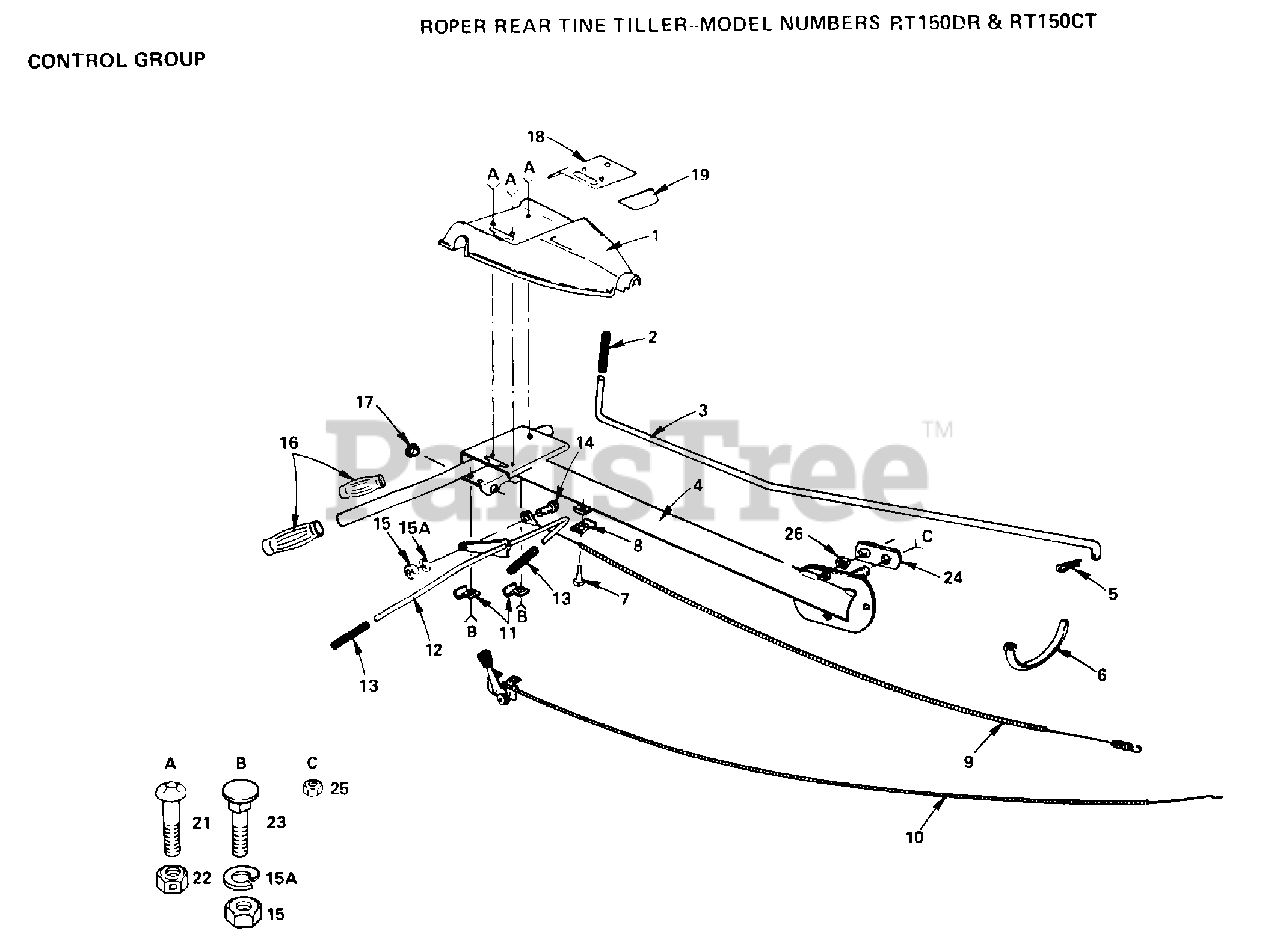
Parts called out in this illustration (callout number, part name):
1	PANEL - CONTROL
2	GRIP TI
5	RETAINER M
6	TIE CABLE CRT
7	SCREW TI
8	CONDIUT CLIP T
9	CABLE.CLUTCH.CRT
10	CTRL-THROTTLE T
13	GRIP BAR CRT
14	SHOULDER BOLT ST
15A	LOCKWASHER
17	GROMMET TI
18	DECAL - INSTRUCTION
19	DECAL - CONTROL PANEL
23	BOLT
24	"NUT, LOCK CRT"
25	LOCKNUT
26	NUT FLANGE CRT
